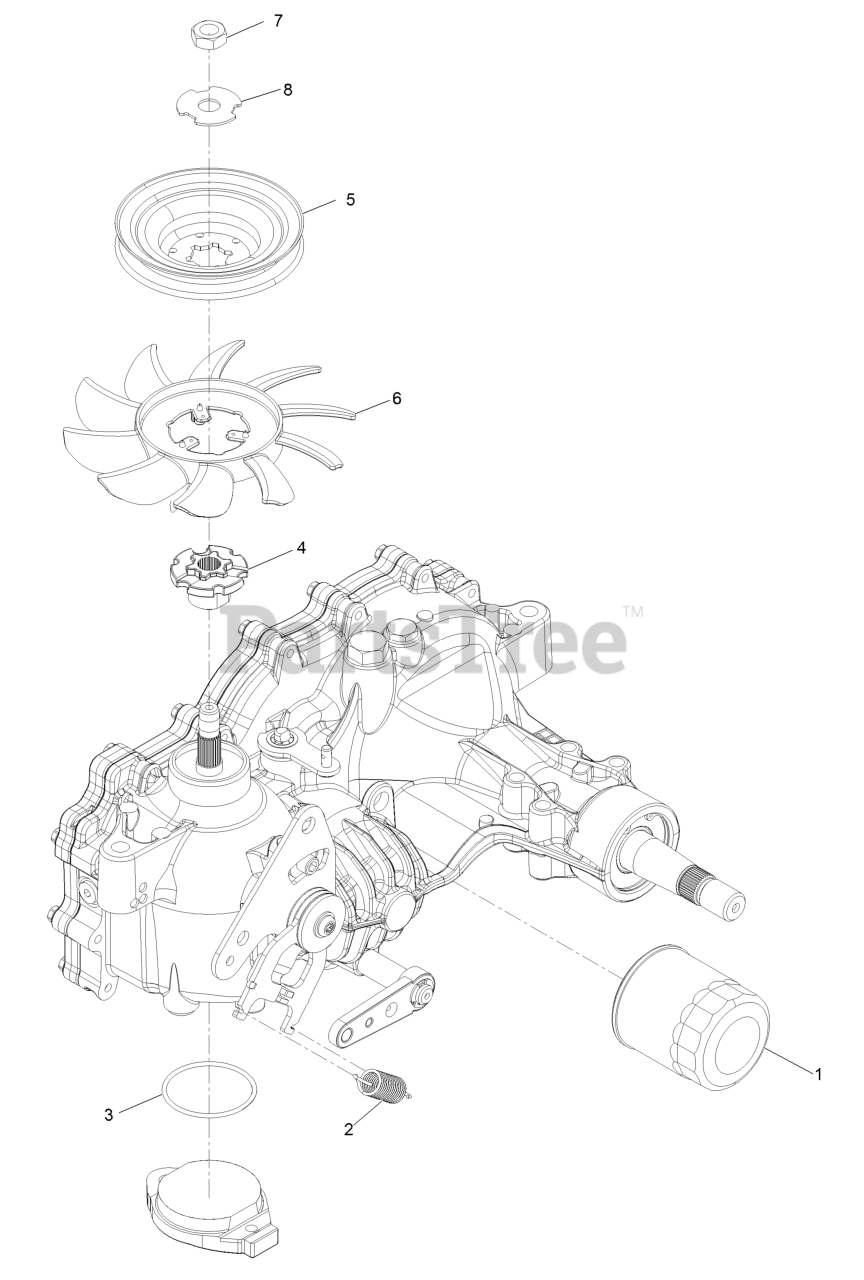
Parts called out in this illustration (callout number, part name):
1	Filter-Hydraulic
2	Spring-Extension Rtn-25 Lbs
3	O-Ring-Charge Seal Cover
4	Hub-Pulley
8	Washer-Slotted
99	Brake Shaft Seal Kit
